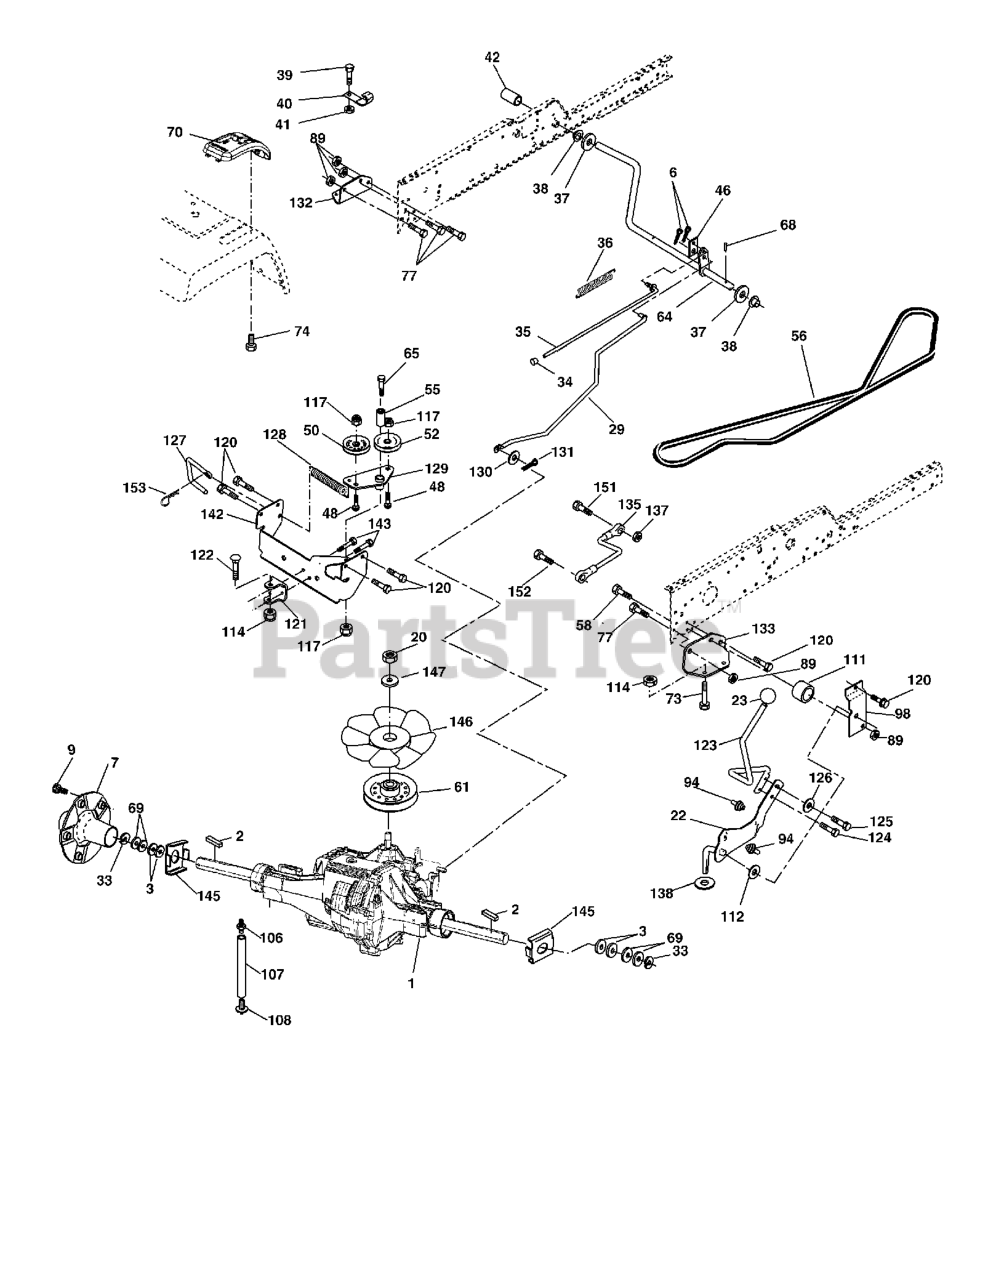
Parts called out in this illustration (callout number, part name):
2	KEY 1/4 X 2.5
3	WASHER T
6	COTTER PIN
7	HUB ASMBLY
9	HUB BOLT
20	NUT.HEX.1/2-20
22	LOWER SHIFT LEVER ASM
23	KNOB.DELUXE.(PISTOL.GRIP).BLAC
29	BRAKE, ROD
33	E RING HYT
34	PLUNGER CAP
35	PARKING BRAKE ROD
36	SPRING DRIVE GROUND
37	WASHER
38	NYLINER
39	Screw, Fin. #10-24 x 1
40	ACTUATOR INTERLOCK SWITCH
41	Nut Centerlock 10-24 unc
42	PEDAL COVER T
46	RETAINER SPRING
48	BOLT
50	FLAT IDLER PULLEY
52	IDLER PULLEY
55	BEARING LT (2 2)
56	BELT, V GROUND DRIVE
58	BOLT.HEX.7/16-14.FINISHED
61	PULLEY, TRANSAXLE
64	SHAFT.ASM.PEDAL.BRAKE
65	BOLT.SHLDR.3/8-16
68	ROLL PIN STD
69	WASHER
70	CONSOLE AUTOMATIC YT.GT
73	BOLT HEX FLGHD 5/16-18X3 GR. 5
74	SCREW.HI-LO.CONSOLE
77	BOLT FIN HEX 7/16-14 X 1
89	Nut, Crownlock Hex 7/16-14 unc
94	FASTENER.XMAS.TREE
98	SHIFT BRACKET
106	O-RING KIT 70110
107	LINE.VENT.HYDRO-GEAR
108	CAP, VENT ASSY
111	SPACER SHIFT LEVER VGTH
112	WASHER NYLON HIGH TEMP
114	NUT.71038.31-18.HEX.NYLOCK
117	NUT LOCK FLG 3/8-16 UNC
120	SCREW, 3/8-16X3/4
121	BRACKET STRAP TORQUE
122	BOLT.5/16-18X2.5
123	ROD SHIFT
124	BOLT.SHOULDER.5/16-18X
125	CAPSCREW.HXHD.FLG.5/16-18X.625
126	WASHER.SRRTD.5/16
127	LINK CONTROL CLUTCH
128	SPRING DRIVE GRND
129	BRACKET ARM IDLER TENSIONING
130	WASHER
131	COTTER PIN
132	BRACKET MTG HYDRO 3500 LH VGT
133	BRACKET MTG HYDRO 3500 RH VGT
135	LINK ASM CONTROL HYDRO 3500
137	LOCKNUT
138	THRUST WASHER
142	STRAP TORQUE HT-3500
143	SCREW 5/16"
145	WASHER.AXLE.FLANGE.HG-3000
146	FAN 7" HYDRO
147	WASHER
151	BOLT
152	BOLT HEX 5/16X1 W/PATCH
153	RETAINER M
